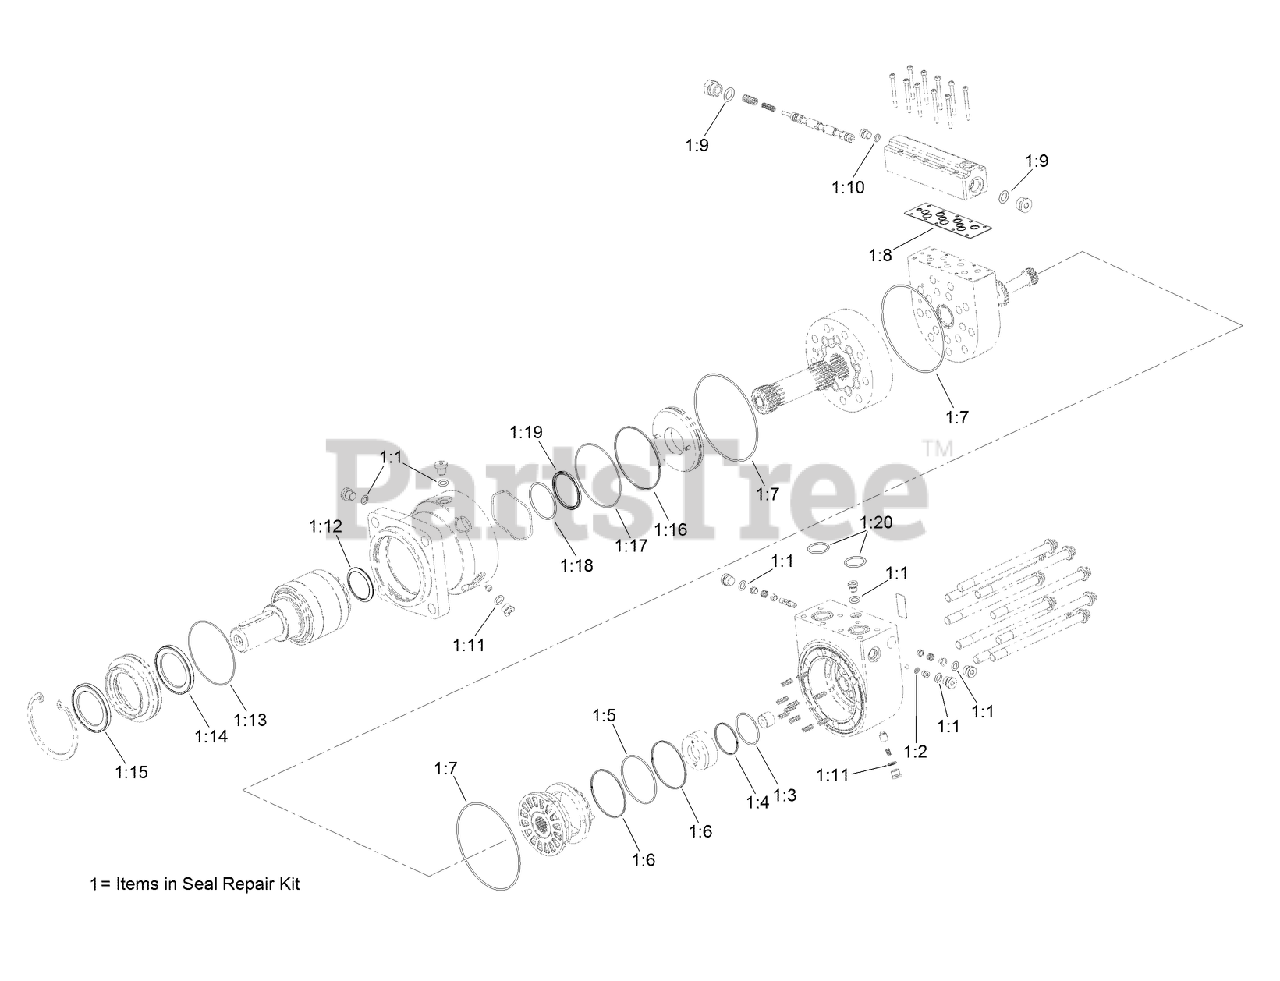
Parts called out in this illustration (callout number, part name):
1	SEAL KIT
1:1	Deck ASM
1:2	Deck ASM
1:3	Deck ASM
1:4	Deck ASM
1:5	Deck ASM
1:6	Deck ASM
1:7	Deck ASM
1:8	Deck ASM
1:9	Deck ASM
1:10	Deck ASM
1:11	Deck ASM
1:12	Deck ASM
1:13	Deck ASM
1:14	SEAL-Shaft
1:15	Deck ASM
1:16	Deck ASM
1:17	Deck ASM
1:18	Deck ASM
1:19	Deck ASM
1:20	Deck ASM
